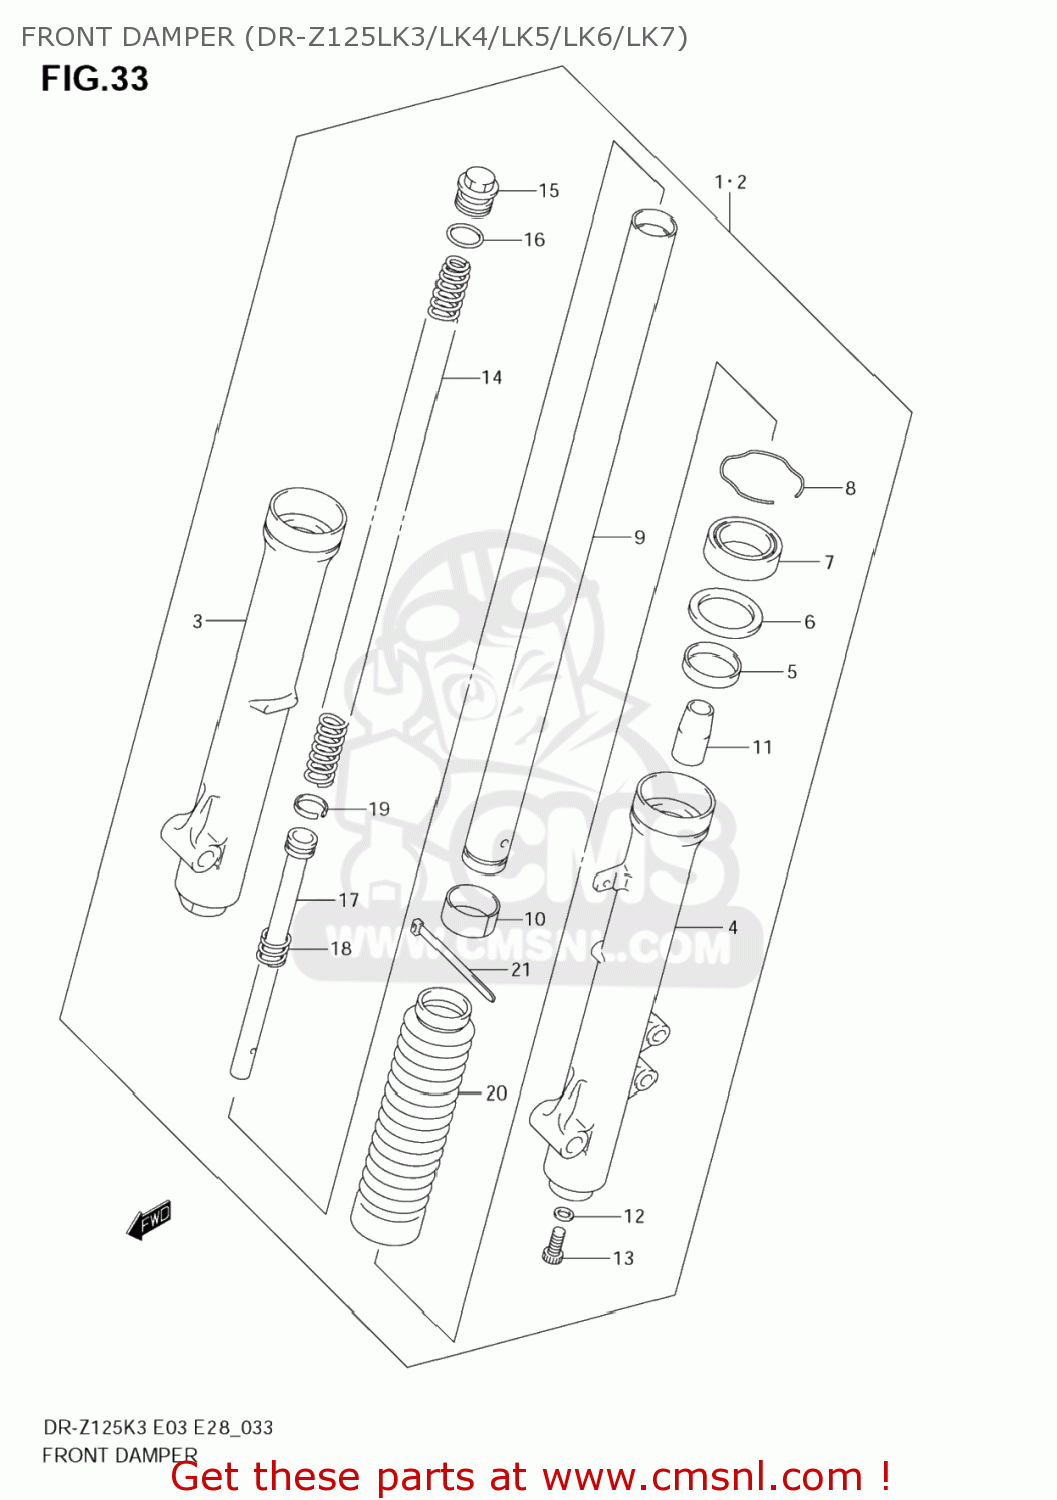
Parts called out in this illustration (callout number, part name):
1	DAMPER ASSY,FR FORK,R
2	DAMPER ASSY,FR FORK,L
3	TUBE,OUTER,R
4	TUBE,OUTER,L
5	BUSH,GUIDE
6	SPACER,SEAL
7	SEAL,OIL
8	SEAL,OIL STOPPER RING
9	TUBE,INNER
10	BUSH,SLIDE
11	PIECE,OIL LOCK
12	GASKET (NAS)
13	BOLT(8X27)
14	SPRING,FR
15	BOLT
16	O RING
17	CYLINDER
18	SPRING,REBOUND
19	RING
20	BOOT
21	BAND
